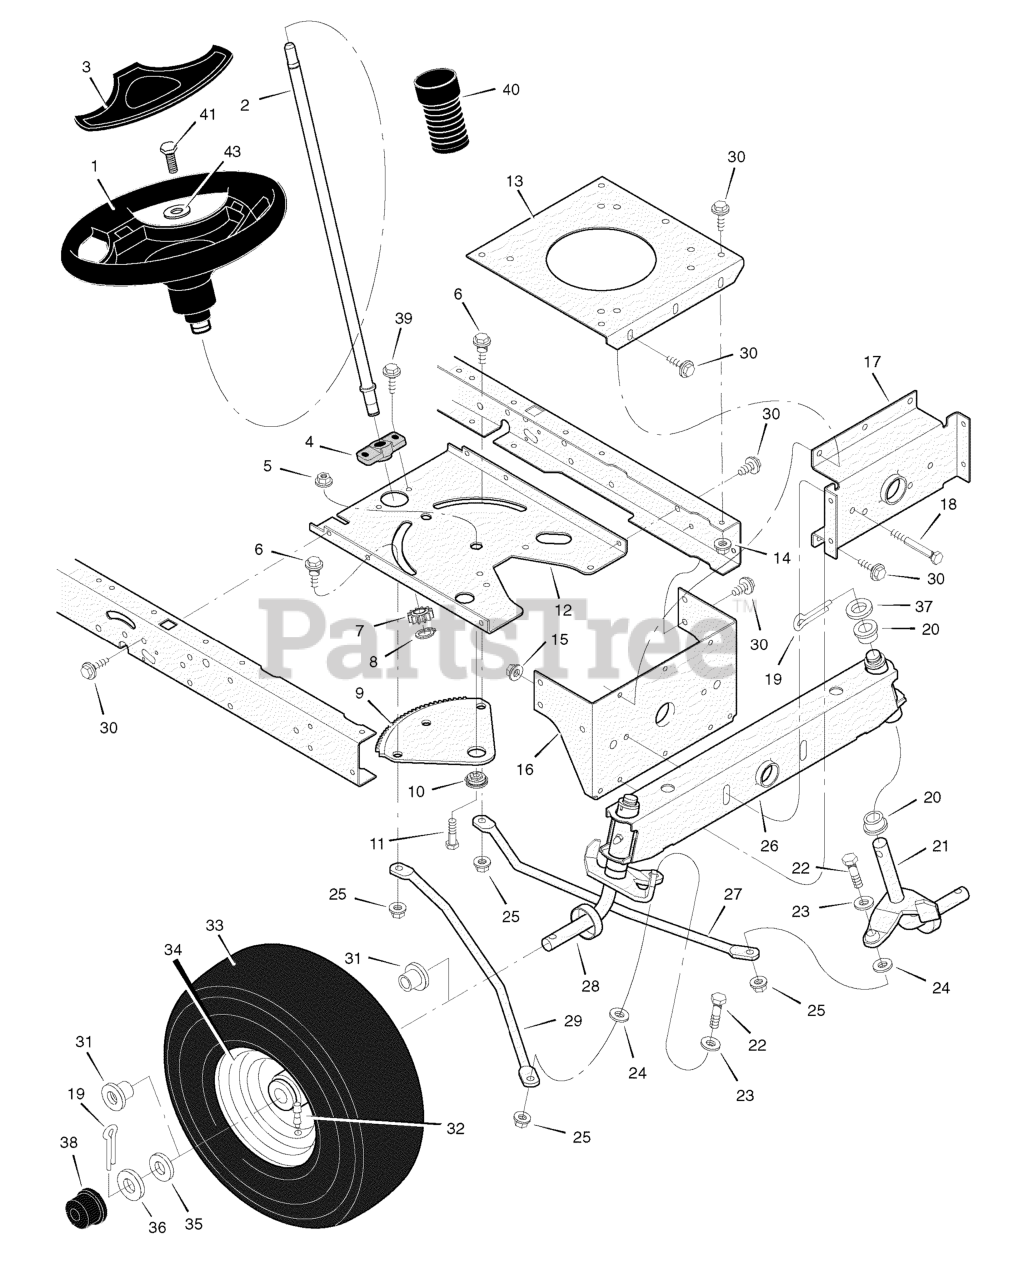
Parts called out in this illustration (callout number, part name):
1	Wheel, Steering
2	Post, Steering
3	Cover, Steering Wheel
4	Bearing
5	Nut, Flange
6	Bolt, Shoulder
7	Gear, Pinion
8	Ring, Snap
9	Gear, Sector
10	Bearing
11	CAPSCREW, Hex Head, 5/16-18 x 1
12	Plate, Steering
13	Plate, Engine
14	Nut, Flange
15	Nut, Flange
16	Bracket, Hanger
17	Axle, Hanger
19	Pin, Cotter
20	Bearing
21	Spindle Assembly, Left
22	Bolt
23	Washer
24	Washer
25	Nut, Flange
26	Axle Assembly
27	Drag Link, Left
28	Spindle Assembly, Right
29	Drag Link, Right
31	Bearing, Wheel
32	Stem, Valve
34	Wheel andTire Assembly
38	Hub Cap
40	Bellows
41	Screw, Hex
43	Washer
